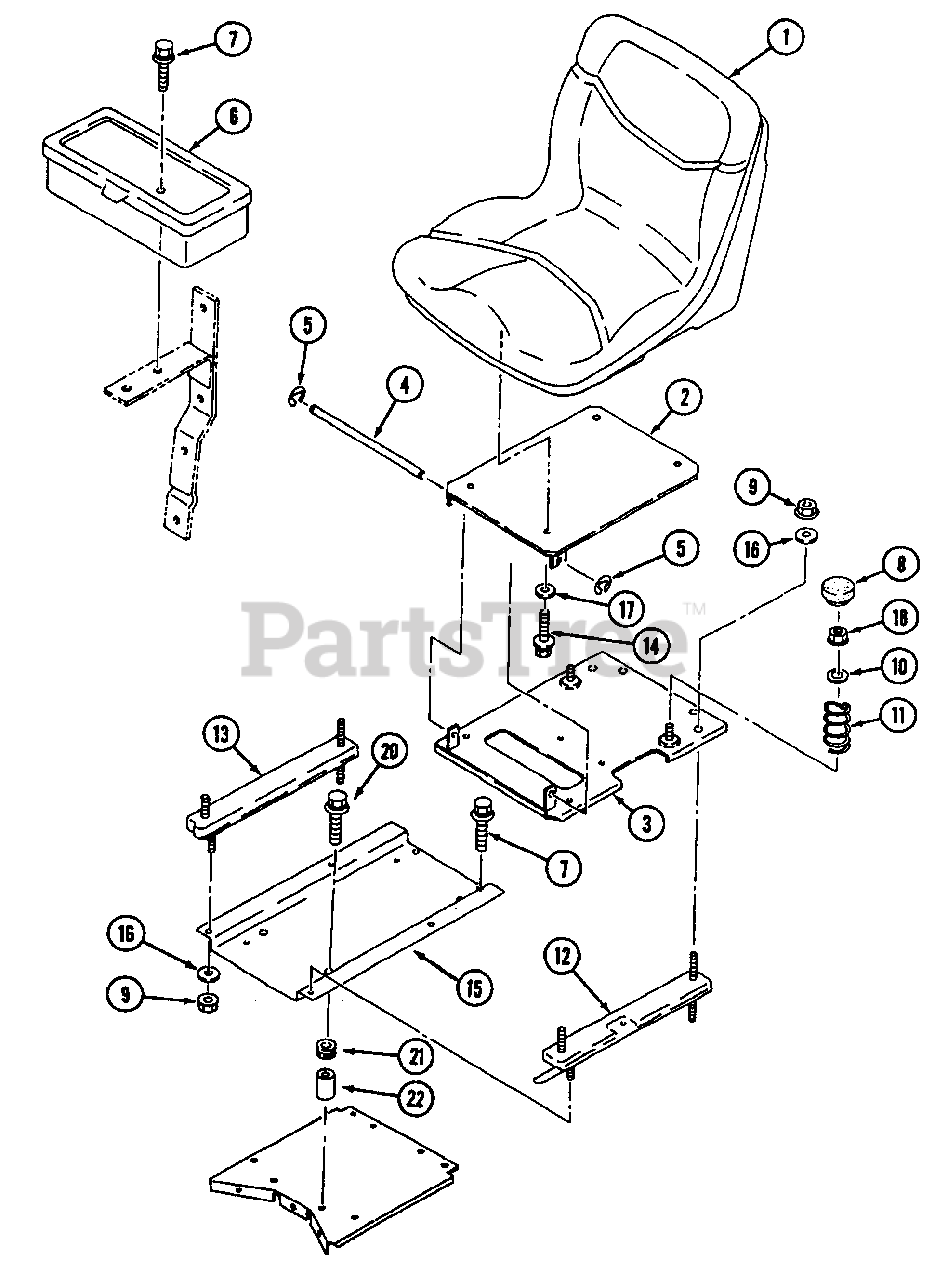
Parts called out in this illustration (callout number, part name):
1	Seat Ass'y.
9	Nut, 8 mm
11	Spring
12	Adjuster, Slide
13	Rail, Slide
16	Washer, Lock
17	Washer, Lock
